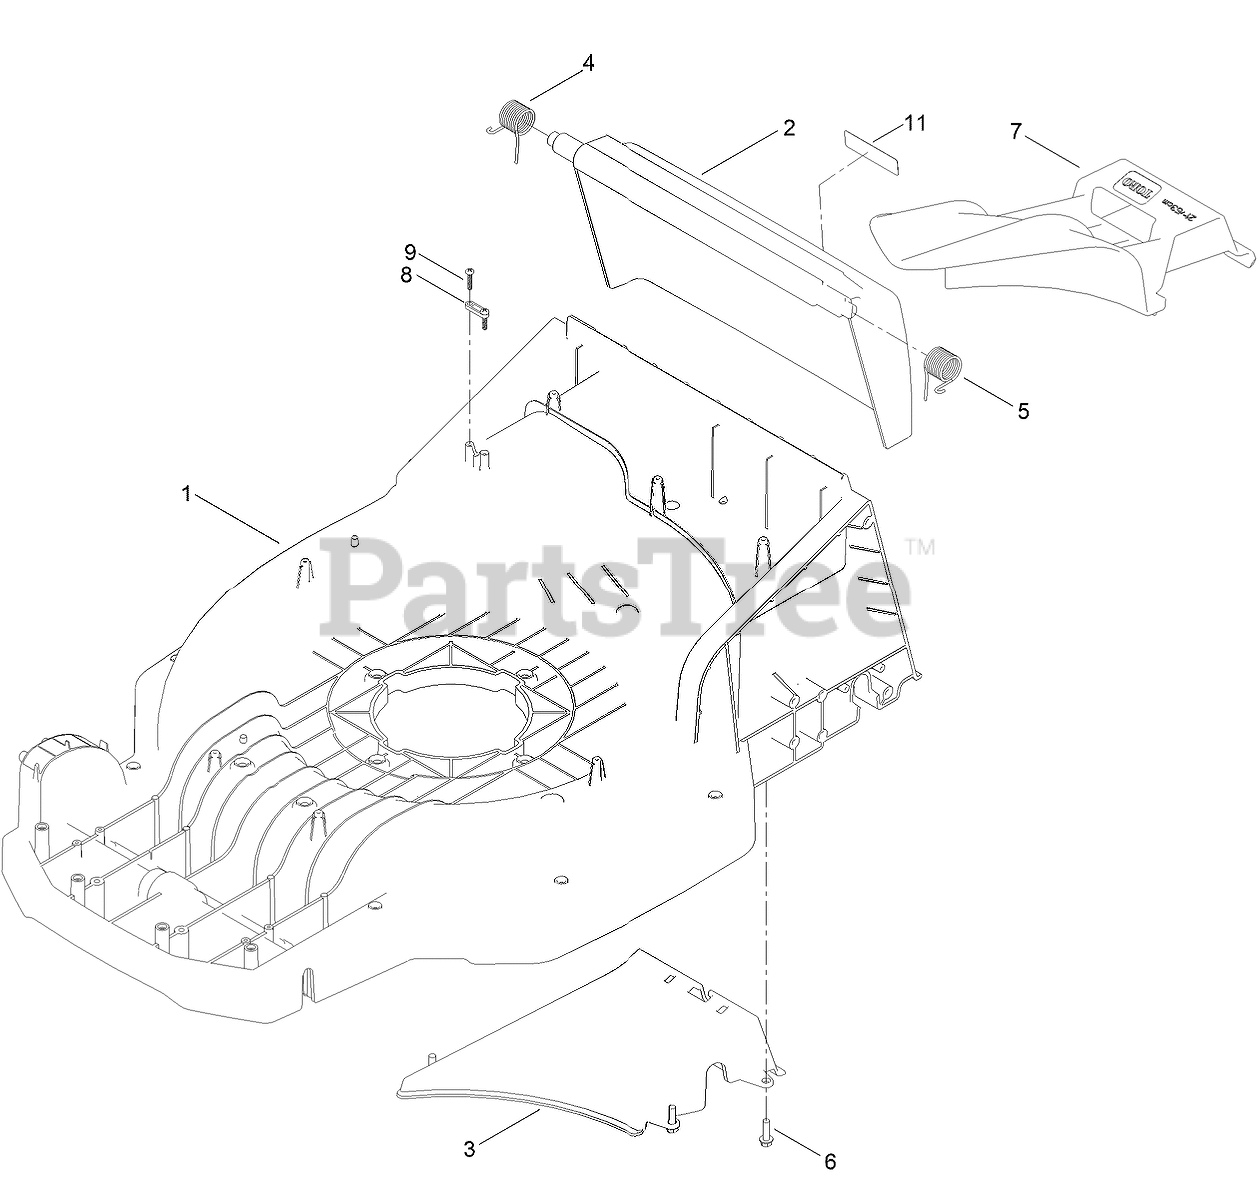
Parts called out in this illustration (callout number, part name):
1	DECK-PLASTIC, 21"
2	ASM-REAR DOOR, IN-MOLD (60V)
3	RAMP-DISCHARGE
4	SPRING-TORSION, RH
5	SPRING-TORSION, LH
6	SCREW-HWH
7	PLUG-DISCHARGE
8	CLAMP-HARNESS
9	SCREW-PPH
11	DECAL-PROP 65, SHORT, TRILINGUAL
